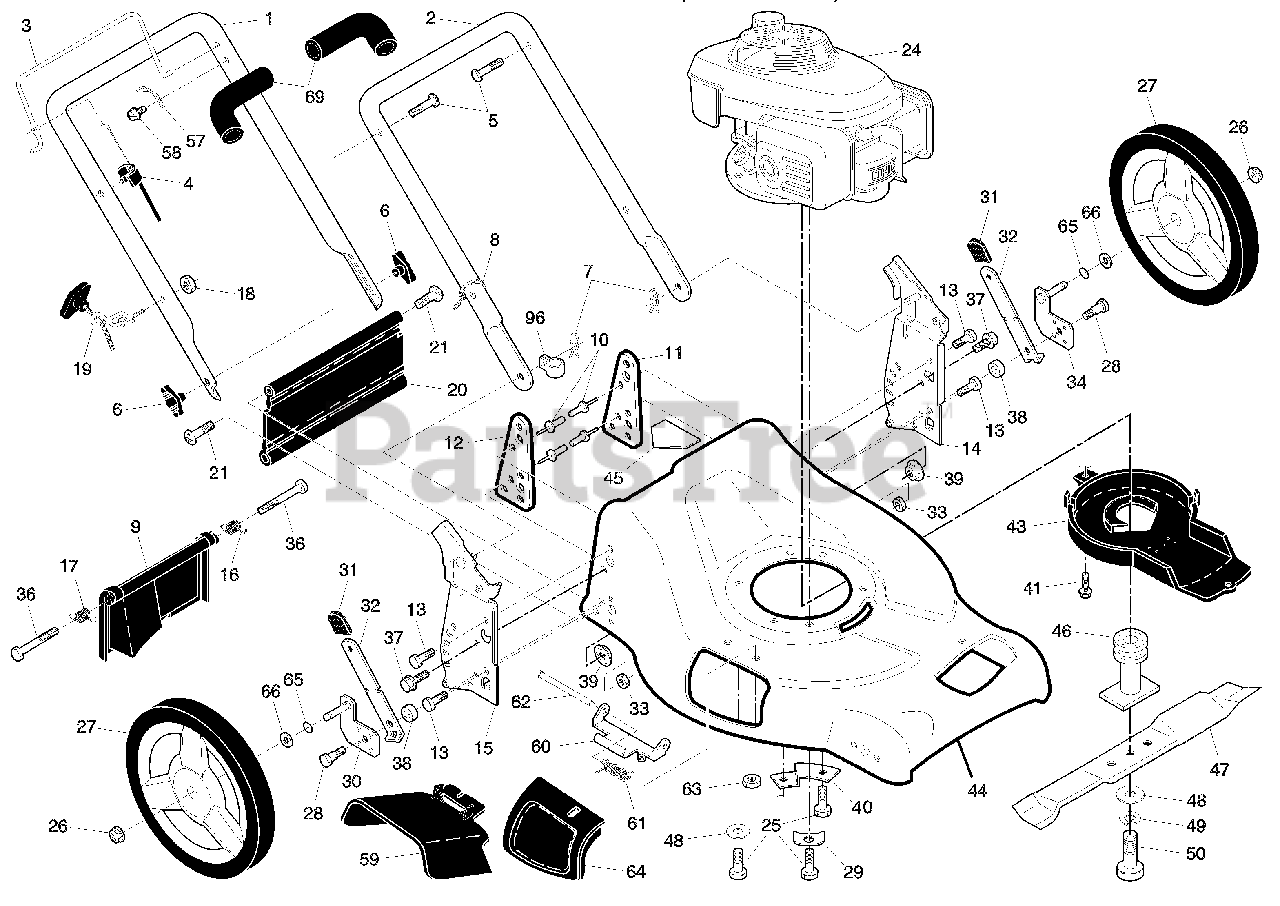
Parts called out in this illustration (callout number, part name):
1	Upper Handle, with Foam Grip
2	Lower Handle
3	Control Bar
4	Engine Zone Control Cable
5	Handle Bolt
6	Handle Knob
7	Hairpin Cotter
8	Wire Tie
9	Rear Door Assembly
11	Support Bracket, LH
12	Support Bracket, RH
13	Screw 1/4-20 x 5/8
14	Handle Bracket Assembly, LH
15	Handle Bracket Assembly, RH
16	Spring, Rear Door, LH
17	Spring, Rear Door, RH
18	Keps Locknut 1/4-20
19	Rope Guide
20	Rear Skirt
21	Screw, Hinge 1/4-20 x 1/2
25	Hex Head Thread Rolling Screw 3/8-16 x 1-1/8
26	Hex Flange Nut
27	Wheel & Tire Assembly, Rear, 12"
28	Shoulder Bolt 5/16-18 x .33
29	Washer, Engine, Zinc-Plated
30	Axle Arm Assembly, Rear, RH
31	Selector Knob
32	Selector Spring
33	Nut, Hex 5/16-18
34	Axle Arm Assembly, Rear, LH
37	Thread Cutting Screw w/Sems 5/16-18 x 3/4
39	Nut, Hex, Flangelock 5/16-18
40	Mounting Bracket, Debris Shield
43	Debris Shield
44	Kit, Lawn Mower Housing
45	Danger Decal
46	Blade Adapter / Pulley
47	Blade, 21"
48	Hardened Washer
49	Helical Washer 3/8-24 x 1-3/8 Grade 8
50	Hex Head Machine Screw 3/8-24 x 1-3/8 Grade 8
57	Upstop Bracket
59	Discharge Defl ector
60	Hinge Bracket
63	Nut, Hex
64	Mulcher Door
66	Washer, Flat 1/2
69	Grip, Foam
96	Clip, Cable
